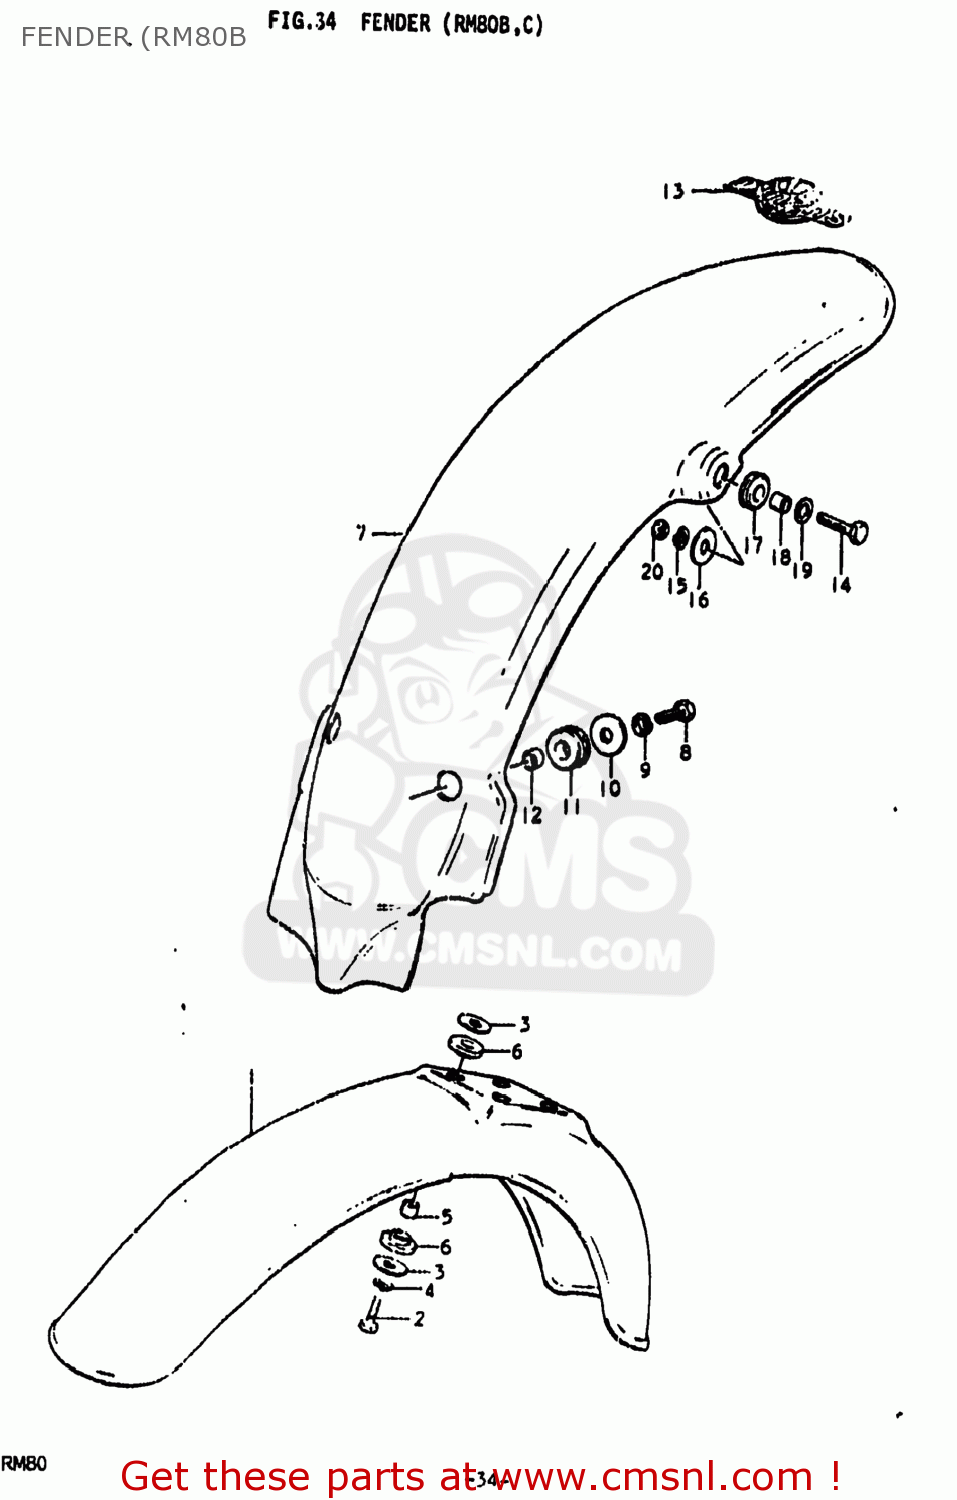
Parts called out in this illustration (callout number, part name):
1	FENDER,FRONT
2	BOLT
3	WASHER (6.5X20X1.2)
4	LOCK WASHER
5	SPACER (6.8X10X10)
6	CUSHION
7	FENDER,REAR
8	BOLT
9	LOCK WASHER
10	WASHER (6.5X20X1.2)
11	CUSHION
12	SPACER(6.1X9X7.5)
14	BOLT
15	LOCK WASHER
16	WASHER (6.5X20X1.2)
17	CUSHION
18	SPACER(6.1X9X7.5)
19	WASHER
20	NUT
